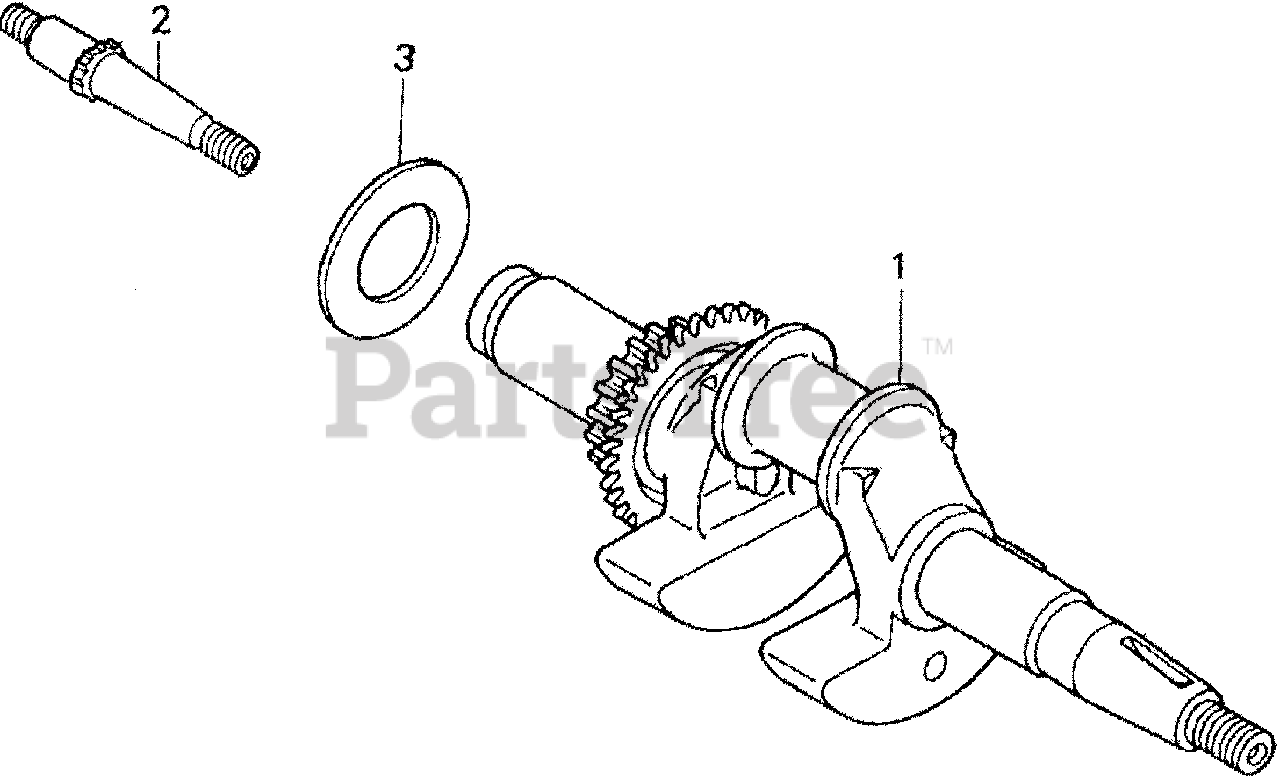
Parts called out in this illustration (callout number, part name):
1	CRANKSHAFT
2	SHAFT, P.T.O.
3	WASHER, THRUST
